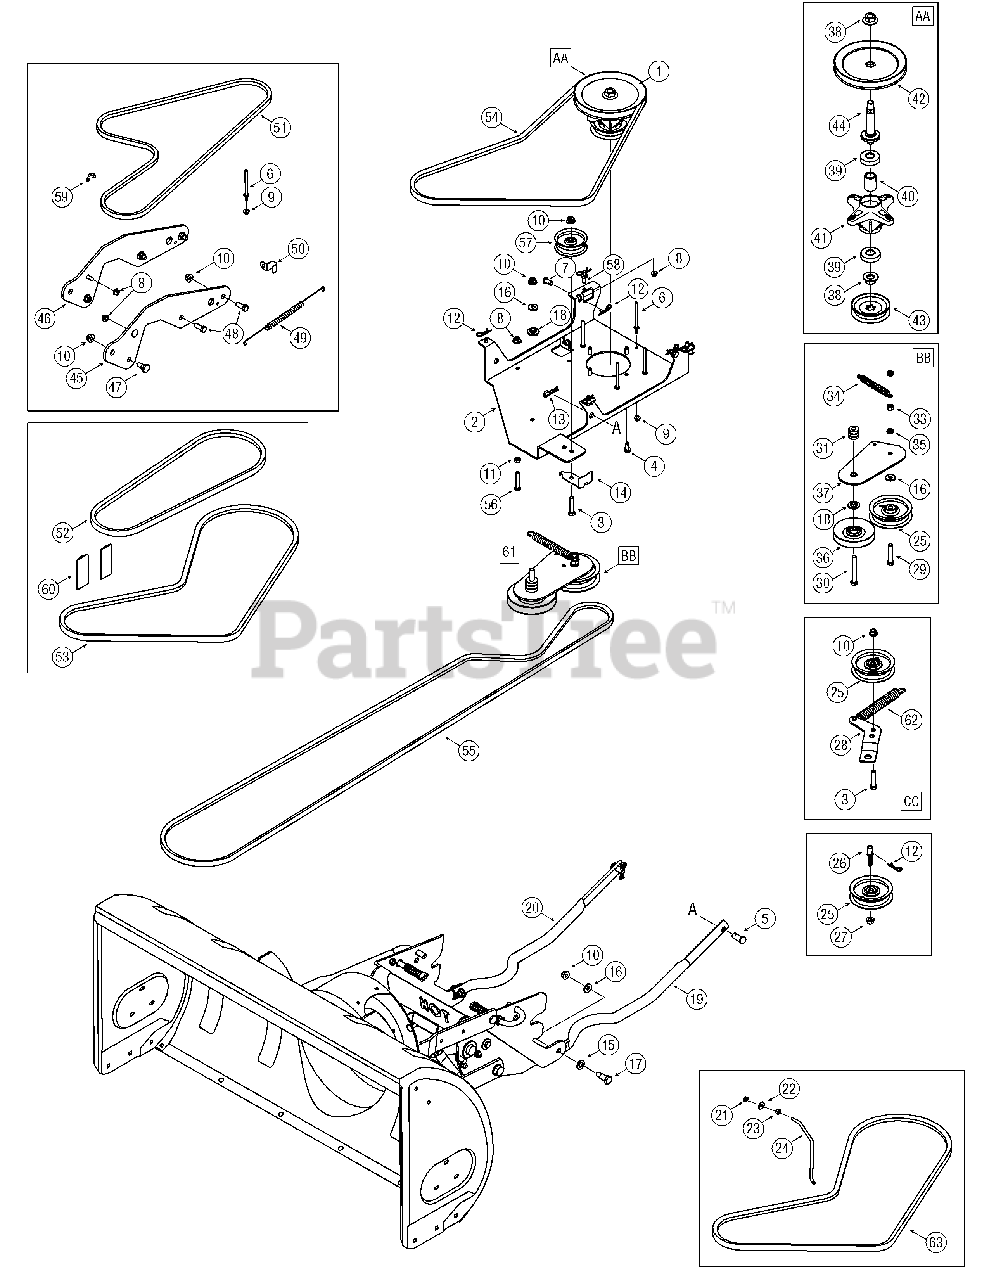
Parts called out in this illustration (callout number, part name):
1	Spindle Assembly (Incl. 38-44)
4	Self Tapping Screw
5	Clevis Pin, .5 x 1.18
6	Belt Keeper Pin
7	Clevis Pin, 3/8 x .75
8	Nylon Hex Lock Nut, 5/16-18
9	Nylon Hex Lock Nut, 1/4-20
10	Hex Flange Lock Nut, 3/8 -16
11	Hex Nut, 5/16-18
12	Click Pin, .092 x 1.64
13	Internal Cotter Pin, .125 x 1.75
14	Belt Guard
15	Flat Washer, .531 x .93 x .09
16	Flat Washer, .38 x .93 x .11
17	Shoulder Screw, 3/8-16
18	Shoulder Spacer, .625 x.169
21	Hex Lock Nut, 1/4-20
22	Bell Washer.265 x .75 x .062
23	Hex Nut 1/4-20
24	Belt Keeper Rod
25	Idler Pulley 3.50 dia.
26	Idler Assembly Spacer
27	Flange Lock Nut 3/8-16
29	Hex Cap Screw, 3/8-24 x 2
30	Hex Cap Screw, 3/8-16 x 3
31	Spacer
32	Nylon Jam Lock Nut, 3/8-24
33	Hex Nut, 3/8-24
34	Extension Spring, .620 x .562
35	Lock Washer, 3/8
36	Idler pulley, 4" Diameter
38	Flange Nut 5/8-18
39	Ball Bearing
40	Spacer
41	Deck Spindle Housing
42	Deck Pulley 7"
43	Pulley 3.75"
44	Spindle Shaft
47	Shoulder Spacer
48	Hex Head Screw 3/8-16 x 1.00
49	Extension Spring .50 x 12.00
50	Clamp 16mm
51	V-Belt
52	Upper V-belt
53	Upper V-belt
54	Upper V-belt
55	V-Belt
56	Hex Cap Screw, 5/16-18 x 1.75
57	Idler Pulley, Flat 2.75 OD
58	Pin 5/16-18
59	Wing Nut 5/16-18
60	Reflector
61	Double Idler Bracket Assembly
62	Extension Spring .91 x 7.33
63	V-Belt
